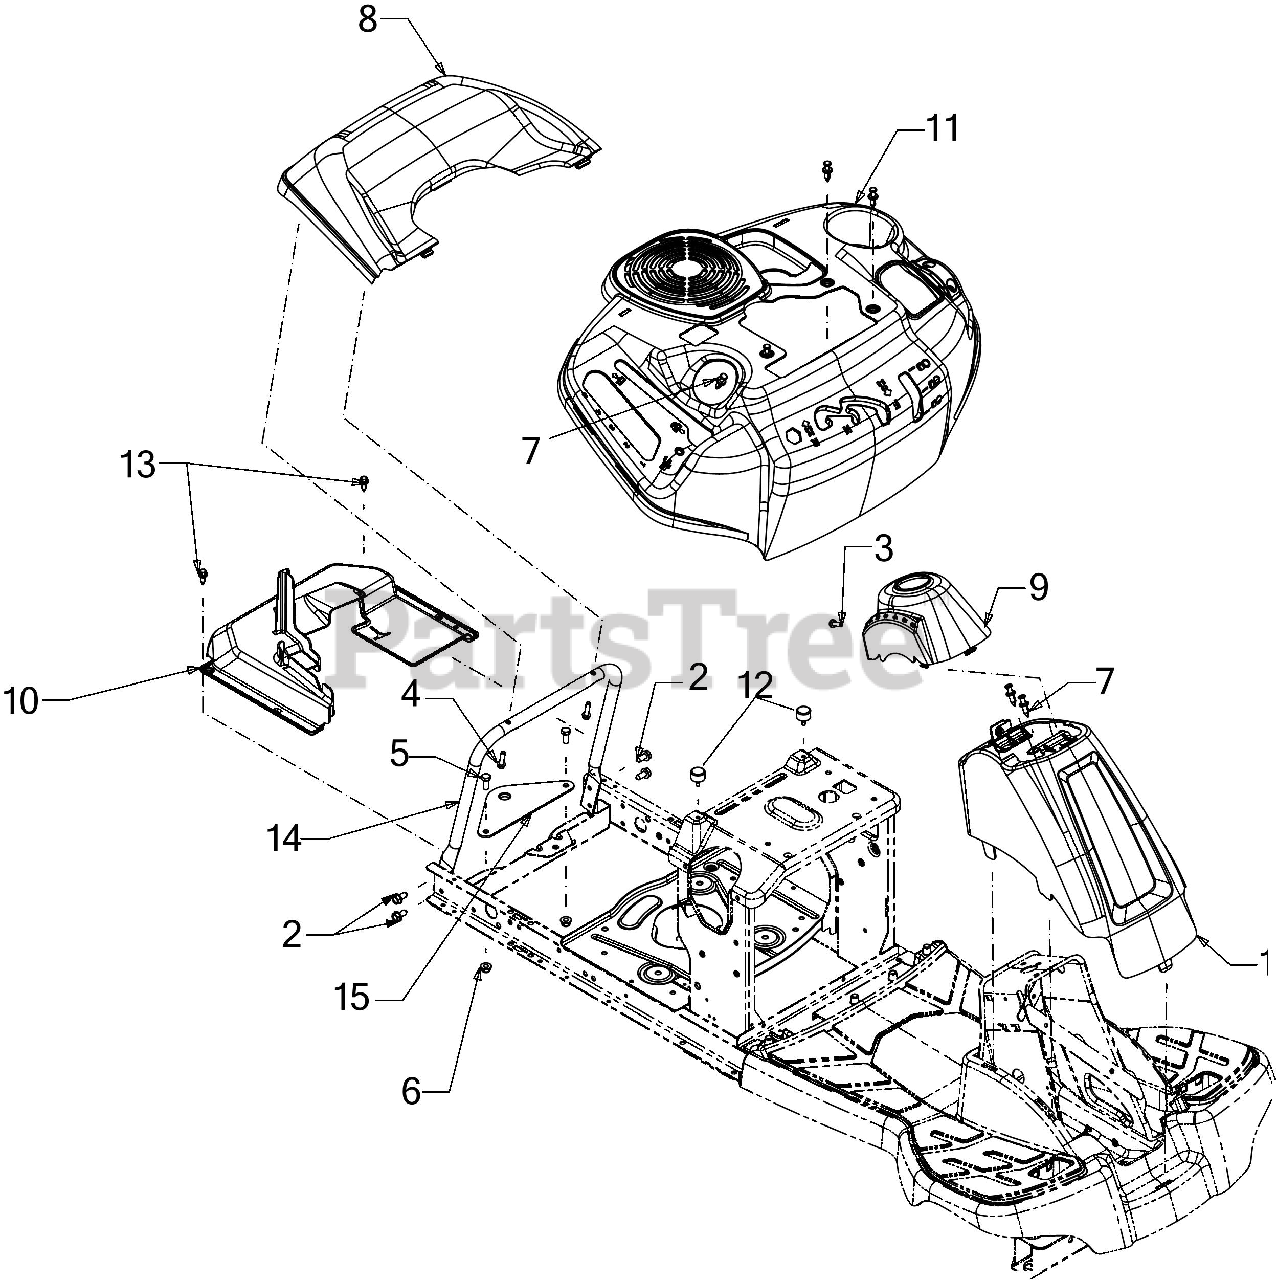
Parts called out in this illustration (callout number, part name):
1	COLUMN COVER ASSEMBLY (CRAFTSMAN RED)
2	SCREW 5/16-18 x .750
3	SCREW 1/4-20X.75
4	SCREW 1/4-15 x 1.00
5	SCREW 5/16-18 x .75 GR5
6	FLANGE LOCK NUT 5/16-18
7	PLASTIC RIVET
8	REAR COVER
9	STEERING COLUMN CAP (SEARS RED)
10	DRIVE OVER REAR
11	FENDER NO/RMC
12	BUMPER .62 DIA x .50
13	SHOULDER SCREW
14	REAR SUPPORT TUBE
15	HITCH PLATE
